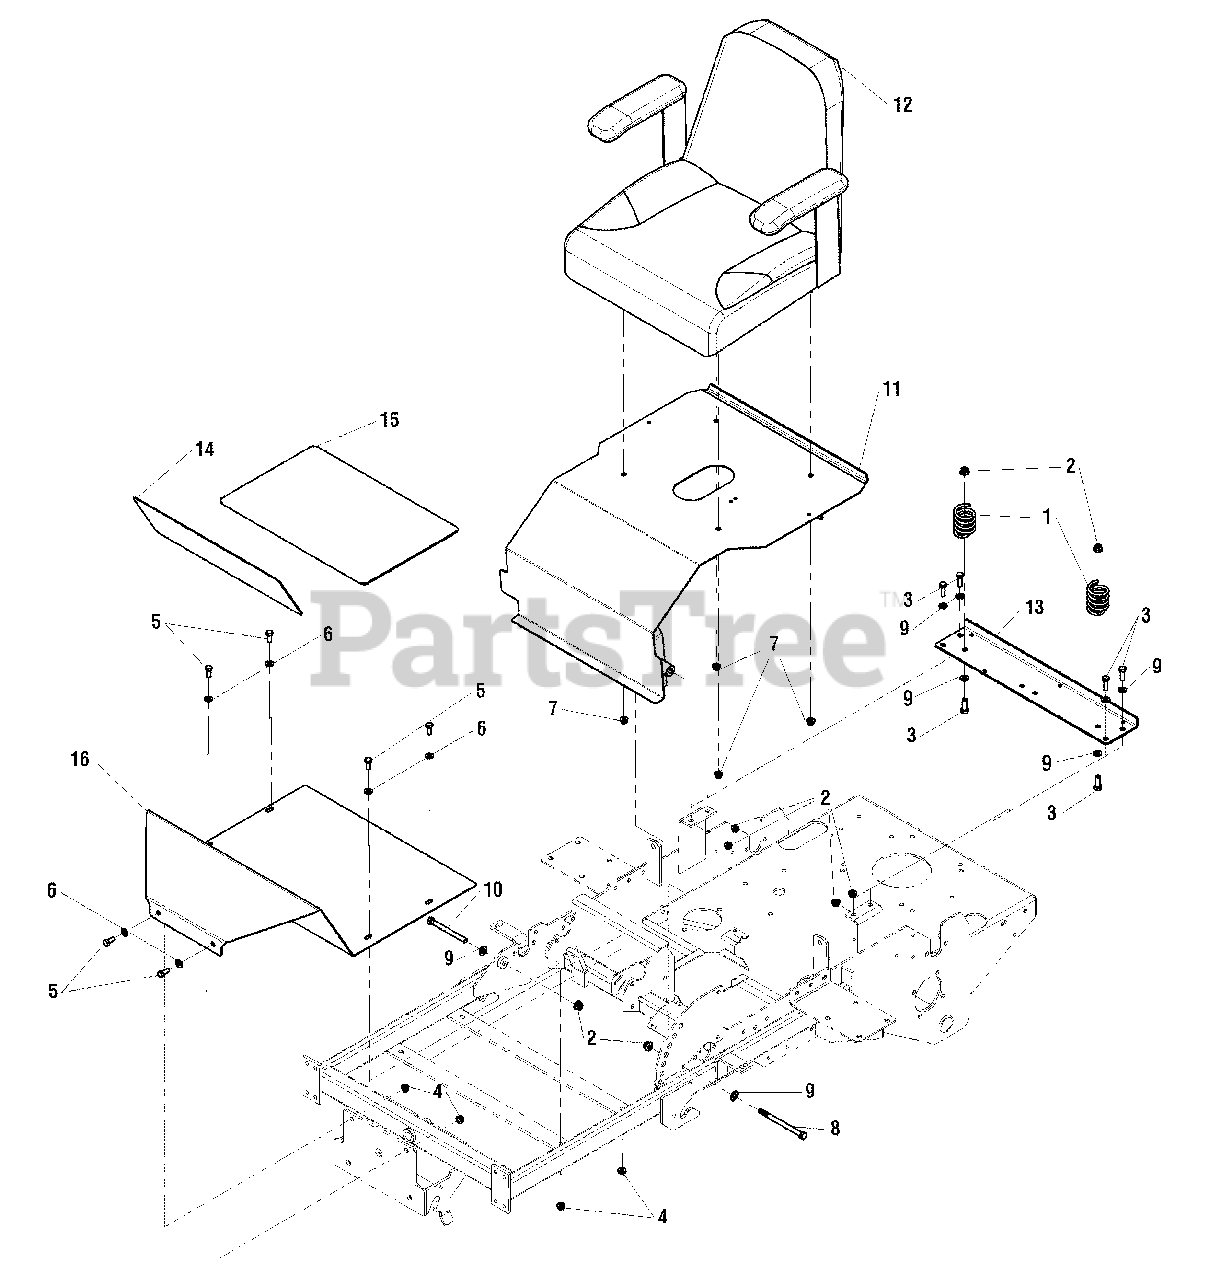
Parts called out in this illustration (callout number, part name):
1	SPRING, SEAT SUPPORT
2	NUT, 3/8-16 HEX NYLOCK FLANGE
3	BOLT, 3/8-16 X 1" GD5 CZ
4	NUT, 5/16-18 HEX NYLOCK FLANGE
5	BOLT, 5/16-18 X 1" GD5
6	WASHER, 5/16" GD.9 FLAT
7	NUT, 5/16-18 HEX NYLON LOCK
8	BOLT, 3/8-16 X 5" GD5
9	WASHER, 3/8 SAE
10	BOLT, 3/8-16 X 4" GD5 CZ
11	WELD, SEAT PLATE - RED
12	SEAT
13	MOUNT, OIL FILTER
14	SAFETY WALK, FLOOR REST, 17.13 X 6.00
15	SAFETY WALK, FLOOR PLATE, 17.13 X 11.50
16	PLATE, FLOOR DETAIL
